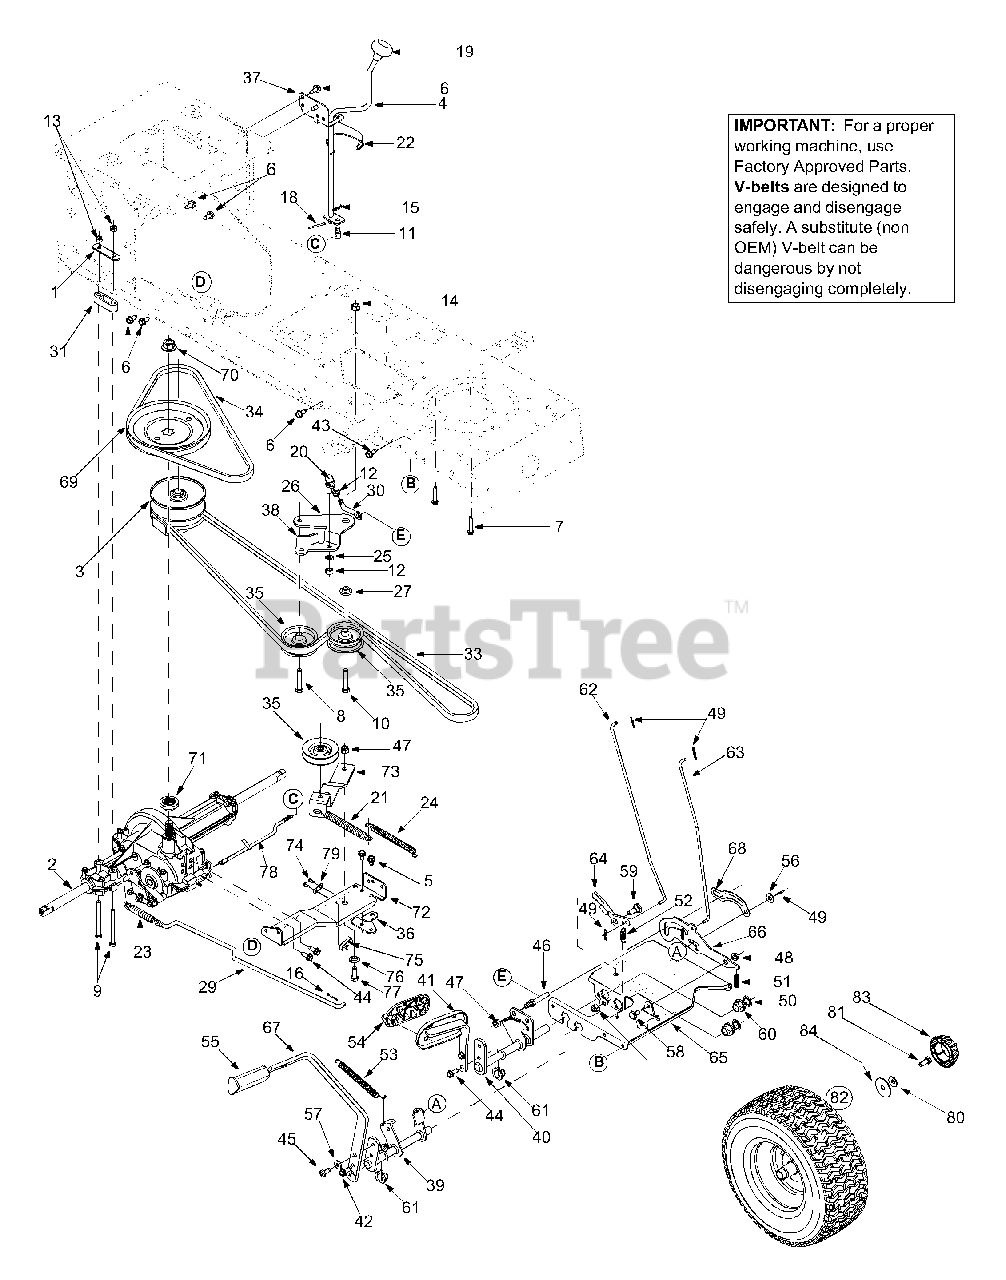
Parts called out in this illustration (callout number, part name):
2	Transmission Assembly
3	Variable Spd. Pulley Assembly
4	Shift Lever Assembly
5	Self-tapping Screw 5/16-18 x 0.5
6	Screw 5/16-12 x 0.75
7	Self-tapping Screw 1/4-20 x 1.25
8	Self-tapping Sems Screw 3/8-16 x 1.5
9	Hex Bolt 5/16-18 x 3.5
10	Hex Bolt 3/8-16 x 2.0
11	Ferrule
12	Hex Nut 3/8-24
13	Hex Lock Nut 5/16-18
14	Flange Lock Nut 3/8-16
15	Hairpin Clip
16	Cotter Pin
17	Hairpin Clip
18	Cotter Pin
19	Shift Knob
20	Ball Joint
21	Extension Spring
22	Spring Clip
23	Extension Spring
24	Extension Spring
25	Lock Washer 3/8
26	Grease
27	Shoulder Spacer
28	Shift Rod
29	Brake Rod
30	Idler Adj. Rod
31	Spacer: Transaxle
32	Spacer
33	V Belt
34	V Belt
35	Flat Idler Pulley
36	Shift Bracket
37	Shift Bracket
39	Brake Control Assembly
42	Self-tapping Screw 5/16-18 x 0.875
43	Screw 5/16-12 x 0.75
44	Screw 5/16-18 x 0.75
45	Self-tapping Screw 5/16-18 x 0.75
46	Pin
47	Hex Lock Nut 3/8-16
48	Flange Lock Nut
49	Cotter Pin
50	Push Nut
51	Compression Spring
52	Extension Spring
53	Extension Spring
54	Control Pad
55	Brake Pad
56	Flat Washer
57	Flat Washer
58	Shoulder Screw
59	Shoulder Screw
60	Hex Flange Bearing
61	Hex Flange Bearing: Split
62	Brake Lock Rod
63	Cruise Control Rod
64	Cruise Latch
66	Lock-Out Bracket
69	Transmission Pulley
70	Flange Nut 9/16-18
71	Pulley Hub
72	Transmission Torque Bracket
73	Idler Bracket
74	Screw #8-18 x 0.5
75	Spring Switch
76	Shoulder Spacer
77	Hex Bolt 3/8-16 x 1.0
78	Shift Rod
79	Insulator Nut Plate
80	Bell Washer
81	Hex Cap Screw
83	Hub Cap
84	Flat Washer
